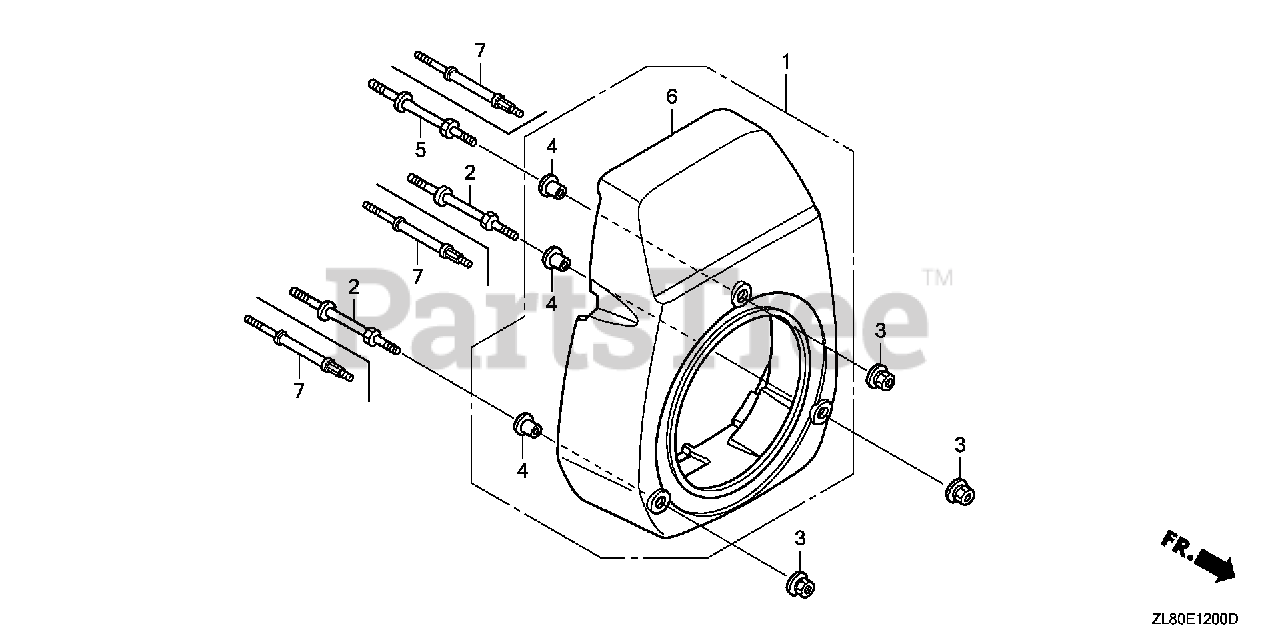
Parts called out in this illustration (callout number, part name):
1	COVER, FAN *NH1* (BLACK)
2	BOLT, STUD (H=42.5MM)
3	NUT, FLANGE (6MM)
4	COLLAR, FAN COVER
5	BOLT, STUD (H=42.5MM)
